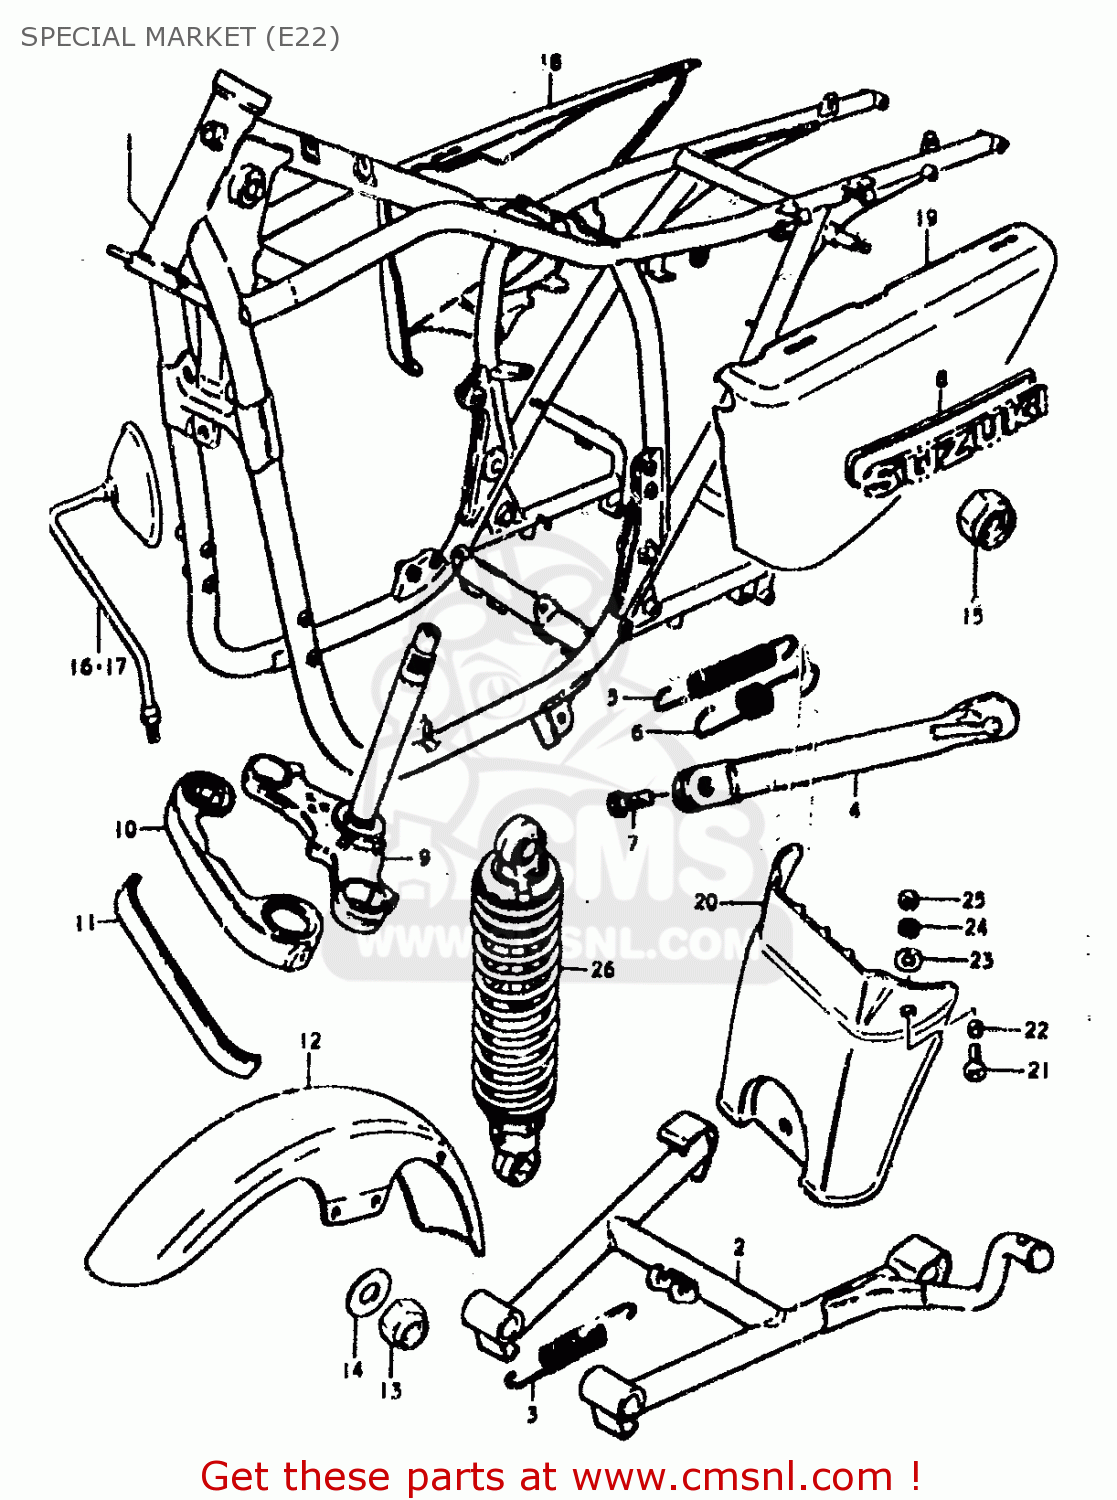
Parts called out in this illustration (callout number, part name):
1	FRAME
2	STAND,CENTER
3	SPRING
4	STAND,PROP
5	SPRING
6	SPRING, OUTER
7	BOLT
8	CUSHION, EMBLEM
9	STEERING STEM
10	COVER,FRONT FORK
11	PROTECTOR, FRONT FORK COVER
12	FENDER,FR
13	NUT
14	WASHER
15	NUT
16	MIRROR ASSY,RH
17	MIRROR ASSY,LH
20	EXTENSION,REAR FENDER
21	SCREW (6X15)
22	SPACER(6.2X8.3X5.7)
23	WASHER(6.5X18X1)
24	LOCK WASHER
25	NUT
26	SHOCK ABSORBER,REAR
